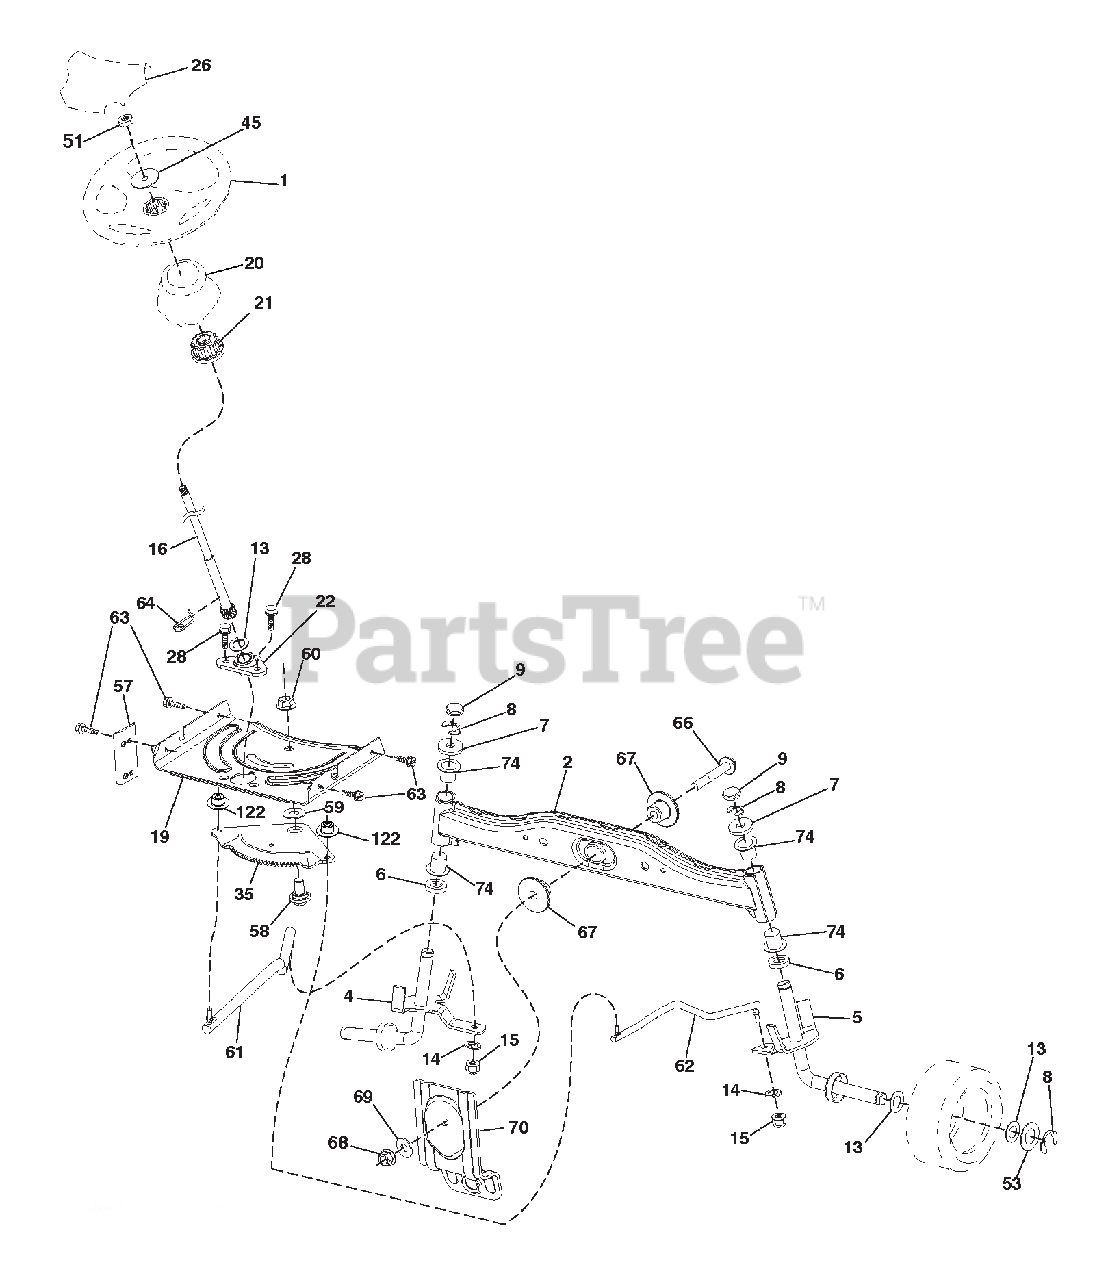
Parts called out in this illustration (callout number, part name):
1	WHEEL STEERING
2	AXLE ASM.WELDED
4	SPINDLE.WELDED.LH.15"TEX
5	SPINDLE.WELDED.RH.15"TEX
6	WAHSER THRUST .75 X 1.230
7	WASHER.25/32 X 1-5/8 X 16GA.
8	RING.KLIP.#T5304-75
9	CAP.SPINDLE.FR.TOP.BLK.
13	WASHER.25/32 X 1 1/4 X 16 GA.
14	Washer, Lock 3/8
15	NUT.CROWNLOCK.3/8-24
16	SHAFT.STEER.3/4 TEX.NON-PLATED
19	PLATE.STEER.DDL.NLT/NGT
20	BOOT.STEERING
21	ADAPTER.WHEEL.STRG..760
22	STEERING SUPT. LOWER
26	CAP WHEEL STEERING HRS/SRS BLK
28	SCREW.HEXWSH THDR3/8-16X3/4.BL
35	GEAR SECTOR.PLATE.DDL.NLT/NGT
45	WASHER.9/16ID X 2-3/8OD.12GZIN
51	NUT.HEX.JAM.TOPLOCK.1/2-20 UNF
53	WASHER.HARDEN..793 X 1.637X060
57	BRACKET.UPSTOP.TEX
58	BOLT.SHOULDER.SECTOR.PIVOT.CFM
59	WASHER.THRUST.SECTOR.STEER.NLT
60	NUT.FLANGE LOCK.5/8-11
61	DRAGLINK.LH.BALLSTUD.DDL.
62	DRAGLINK.RH.BALLSTUD.DDL
63	SCREW.5/16-18X3/4.SMGML.TAP/BL
64	RETAINER.CLIP.SPRING.STEERING
66	BOLT.HEX.FGHD.7/16-14 X 3.SERR
67	BUSHING.PM.FRONT AXLE
68	NUT.LOCK.FLANGE.7/16-14.GR5
69	WASHER.1.5 X .505 X .118
70	BRACKET.DECK.SUSPENSION.FRONT
74	BEARING COL STRNG BLK
122	CAP GEAR SECTOR
